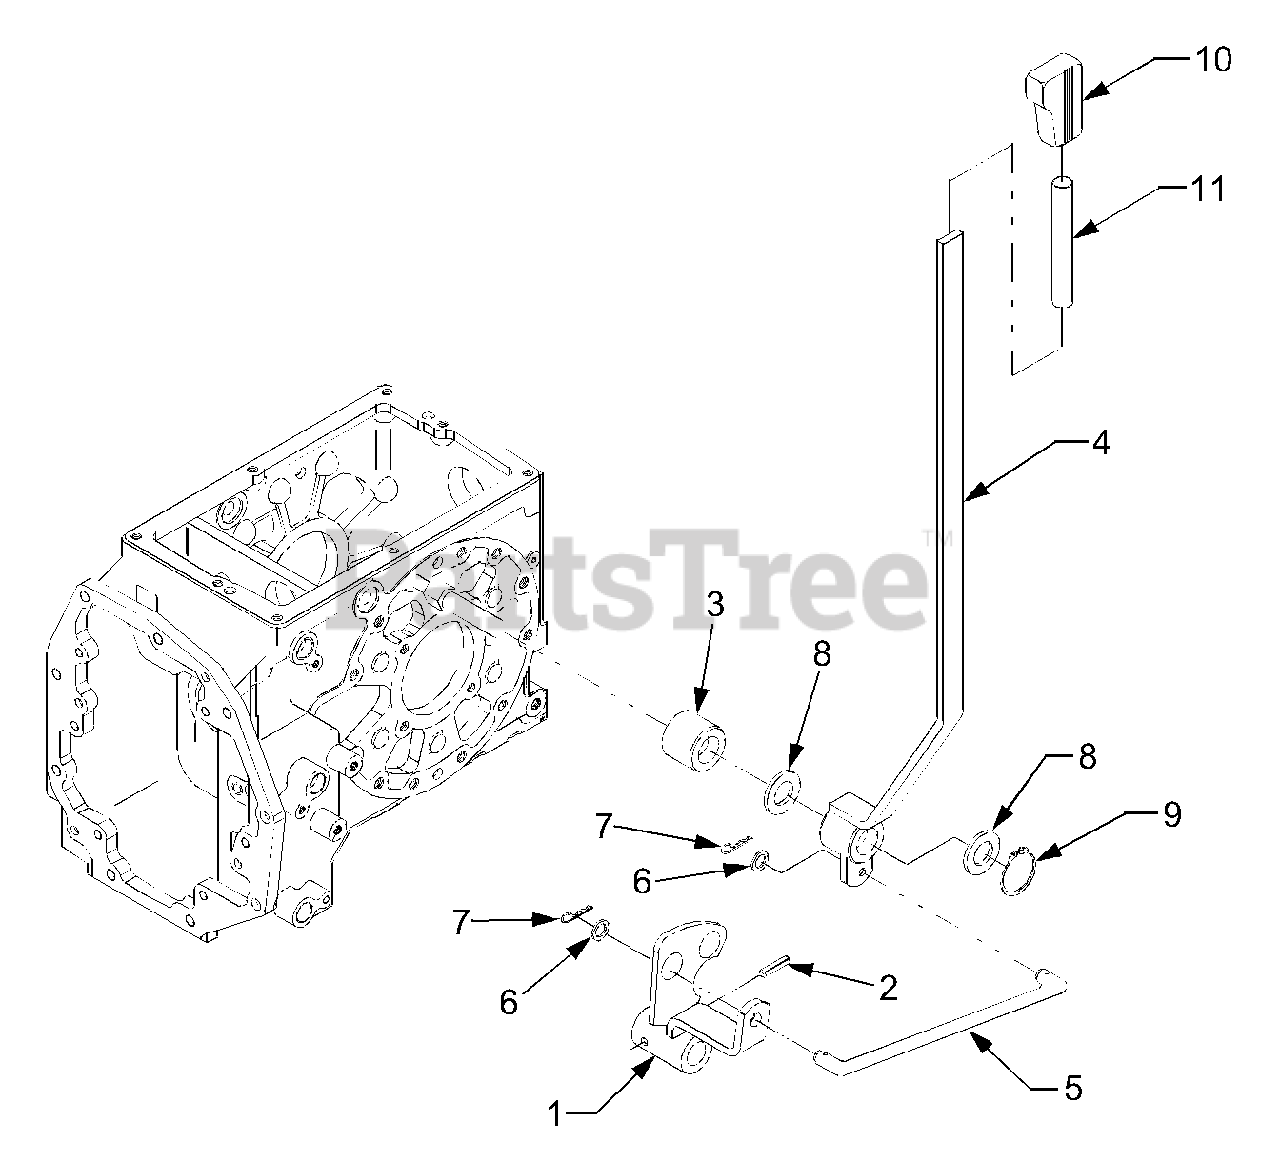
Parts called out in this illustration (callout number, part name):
1	Lever 1, Hi-Low
4	Lever, Hi-Low Shift
6	Washer, Plain
8	Washer, Plain
